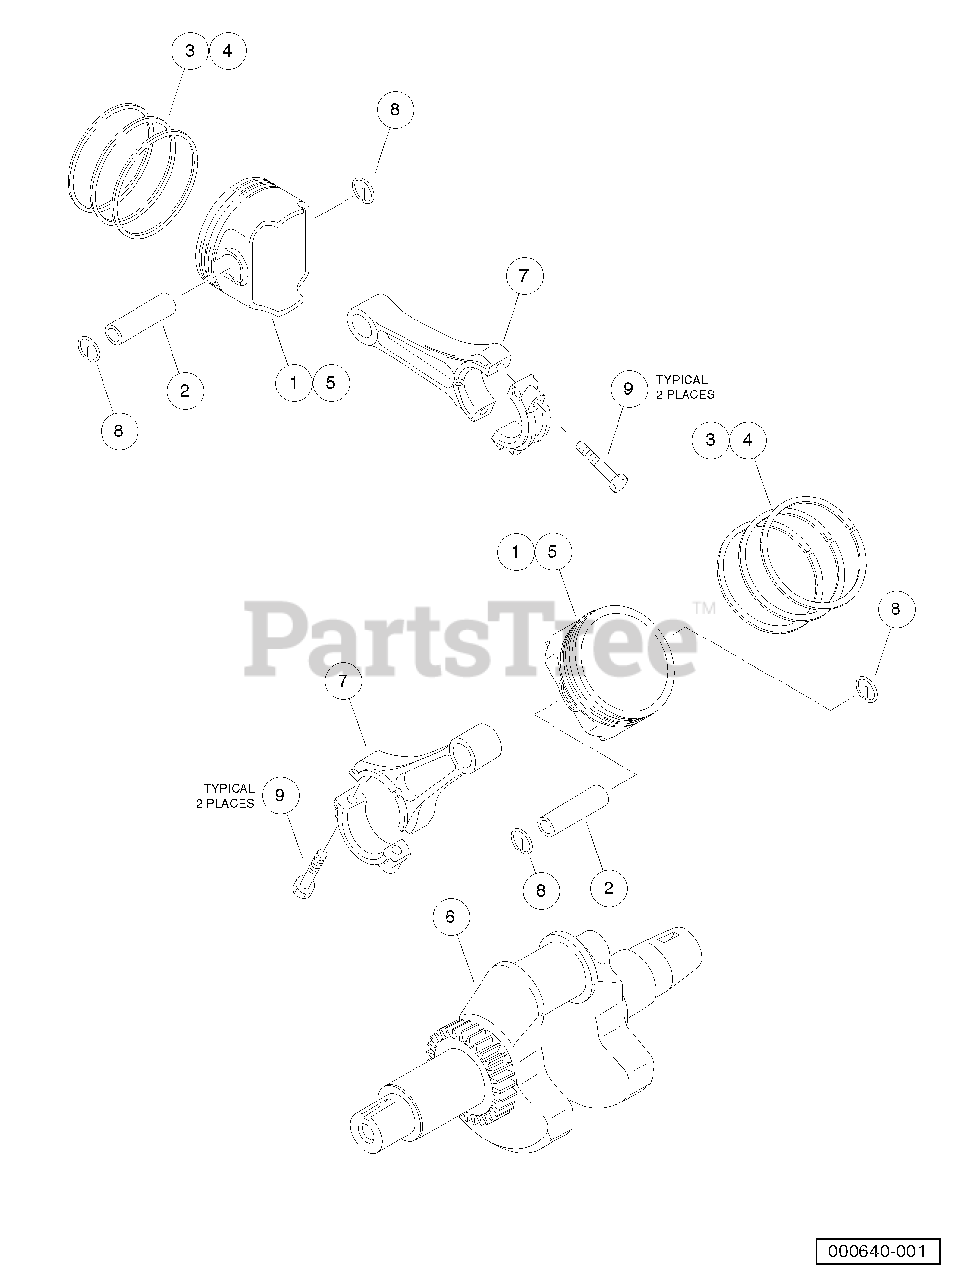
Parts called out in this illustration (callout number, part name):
1	Piston, Engine, Right, Fh
2	Pin, Piston, Engine, Fh
3	Ring, Set, Piston, Fh
4	Ring, Set, Piston L, 0.50, Fh
5	Piston, Engine L, 0.50, Fh
6	Crankshaft, Comp, Fh
7	Kit, Rod, Connecting, Fh
8	Ring, Snap, Pin, Piston, Fh
9	Bolt, Flg, M6 X 1.00 X 35
